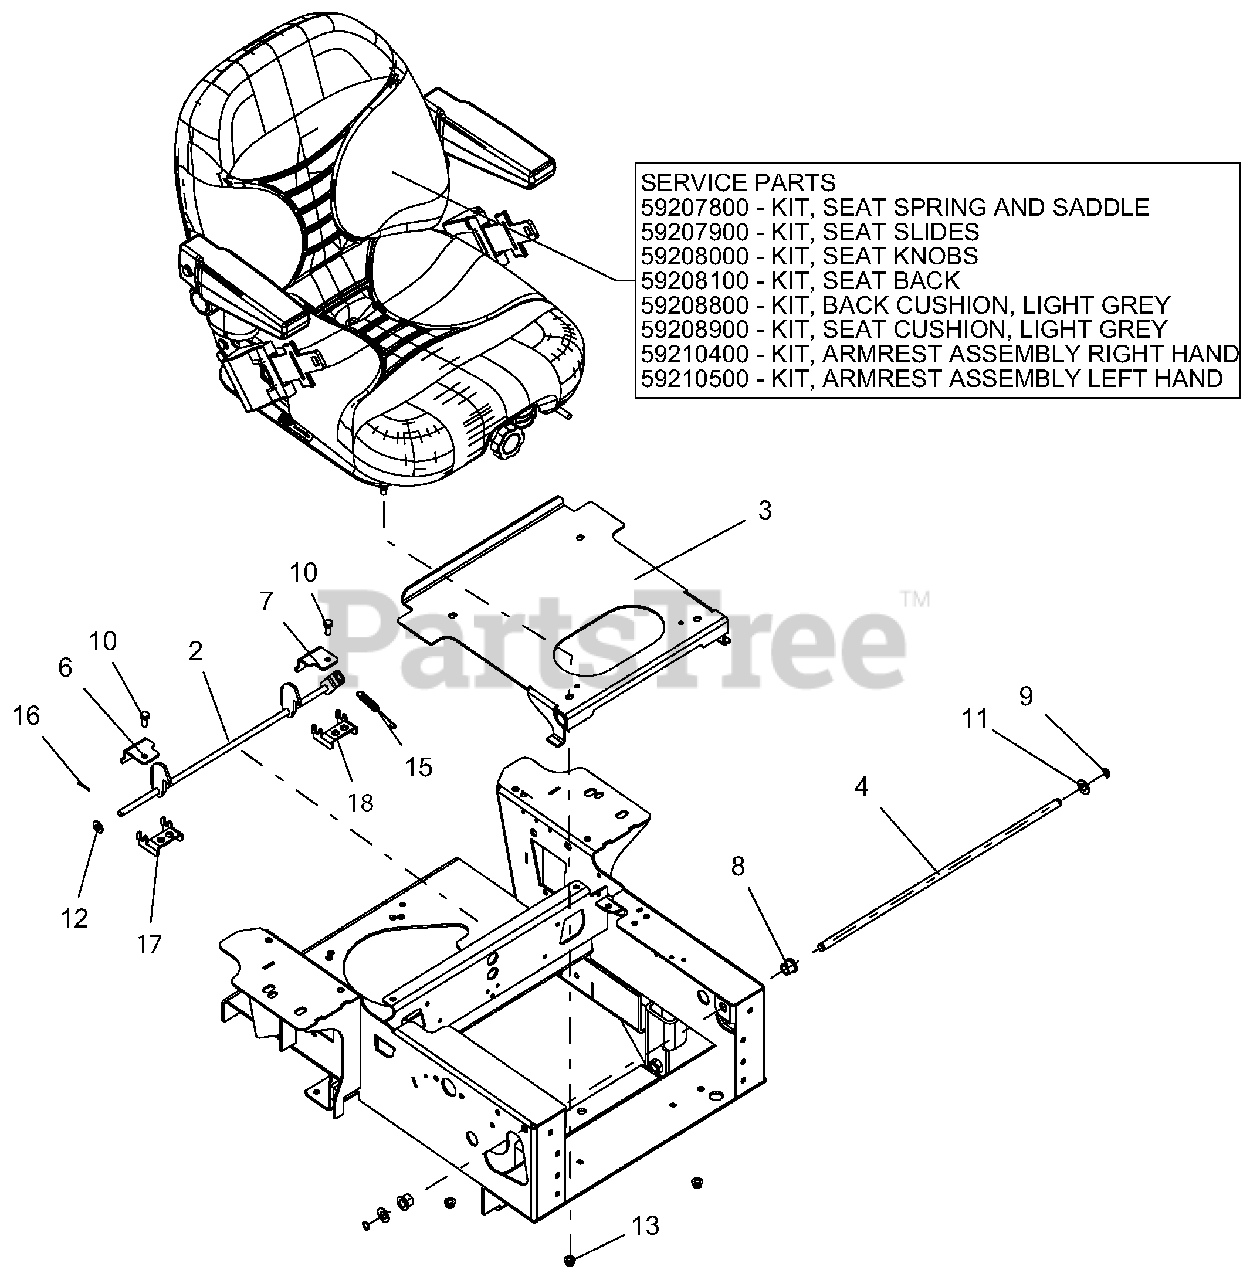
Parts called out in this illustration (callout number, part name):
2	WLDMT, PRO-TURN SEAT LATCH-BLACK
3	WLDMT, PRO-TURN 100 SEAT PLATE - BLK
4	SHAFT, PT/PT100 SEAT PIVOT
6	MOUNT, PT/PT100 RH TOP SEAT LATCH-BLACK
7	MOUNT, PT/PT100 LH TOP SEAT LATCH-BLACK
8	BSHG, SHLDR EP .358-16X.30 HEX YZ
9	RG-RTNG-EXT .500x.050
10	BLT-HEX .31-18X.75 GR5 YWZC
11	WSHR-FL-STL .531X1.000X.063 YWZC
12	WSHR-FL-STL.406X.812X.065 YWZ
13	NUT-LK-NYL-FLG .31-18 YWZC
15	SPRG, EXTENSION
16	@PIN-CTR .09X.75 EXTPRSQCT YWZ
17	WLDMT, PT/PT100 RH SEAT LATCH MOUNT-BLACK
18	WLDMT, PT/PT100 LH SEAT LATCH MOUNT-BLACK
